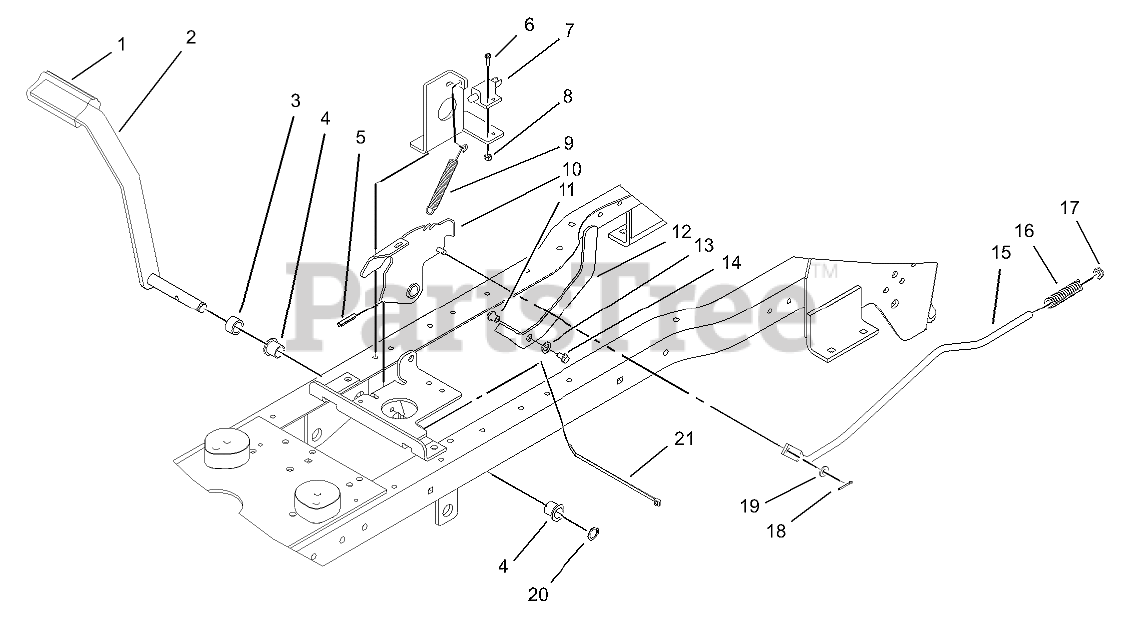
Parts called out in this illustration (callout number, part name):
1	PAD-PEDAL
2	BRAKE PEDAL ASM
3	SPACER-BRAKE
4	BUSHING-FLANGE
5	PIN-SPRING
6	SCREW-SHH
7	SWITCH-INTERLOCK
8	NUT-LOCK
9	SPRING-EXTENSION
10	Brake ASM
11	POST-MOUNTING, LINKAGE
12	Lever-Brake, Parking
13	SPACER-BRAKE, PARKING
14	SCREW-HHF
15	ROD-BRAKE
16	SPRING-COMPRESSION
17	NUT-HEX
18	PIN-COTTER
19	WASHER-FLAT
20	RING-RETAINING
21	TIE-CABLE
